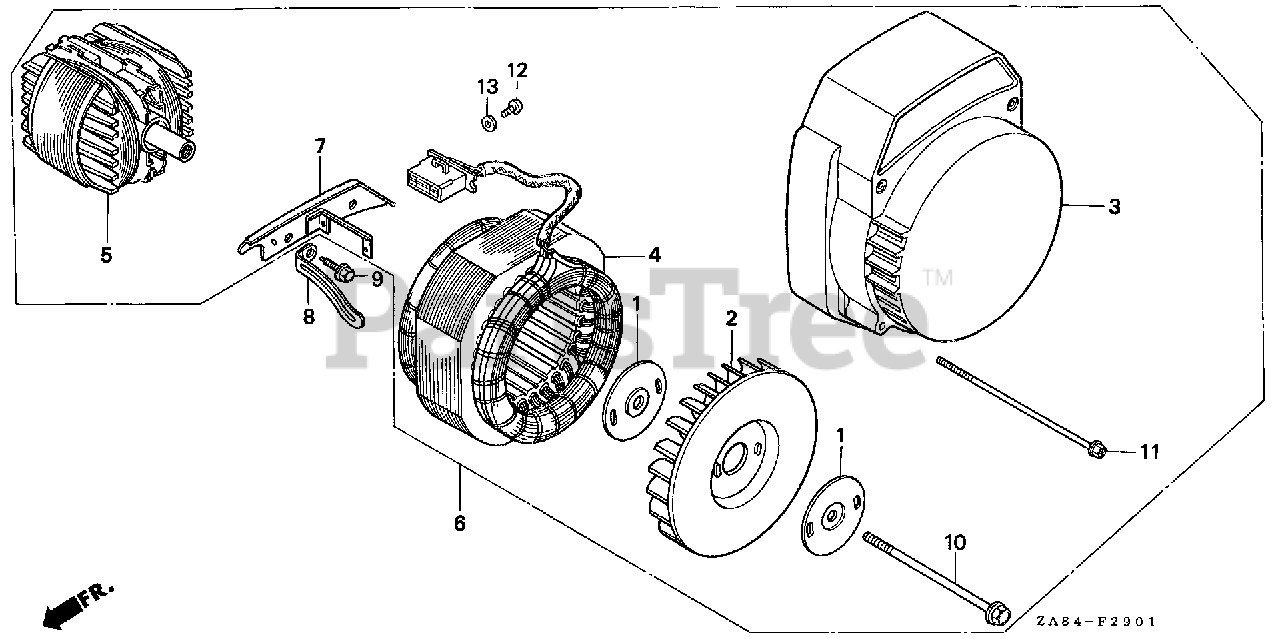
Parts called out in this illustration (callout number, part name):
1	PLATE, FAN SETTING
2	FAN, COOLING
3	COVER, GENERATOR FAN
4	STATOR ASSY.
6	GENERATOR ASSY.
7	PLATE, CONNECTOR SETTING
9	BOLT, FLANGE (5X10)
10	BOLT, FLANGE (8X92)
11	BOLT, FLANGE (6X98)
12	SCREW, PAN (3X8)
13	WASHER, PLAIN (3MM)
